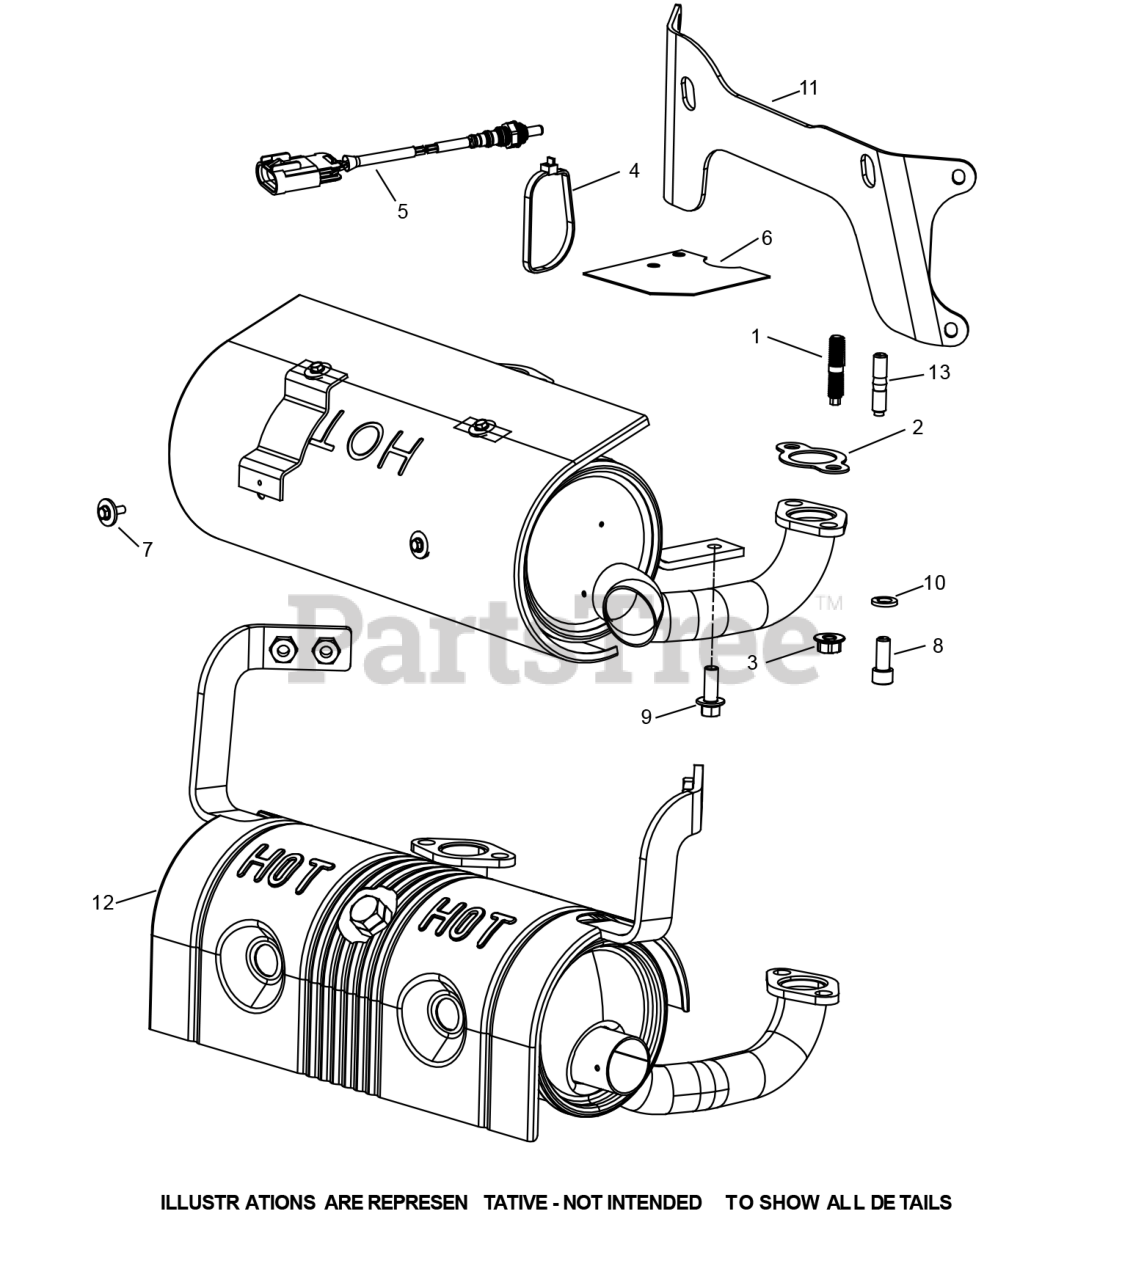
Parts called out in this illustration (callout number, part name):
1	EXHAUST STUD
2	EXHAUST MANIFOLD GASKET
3	HEX FLANGE NUT LOCK M8
5	OXYGEN SENSOR
6	DEFLECTOR-
7	SCREW-SEMS DRILL
8	SCREW-SOCKET HEAD
9	SCREW FLG M8X1.25X20
10	WASHER
12	MUFFLER ASSEMBLY HORIZONTAL (EFI)
